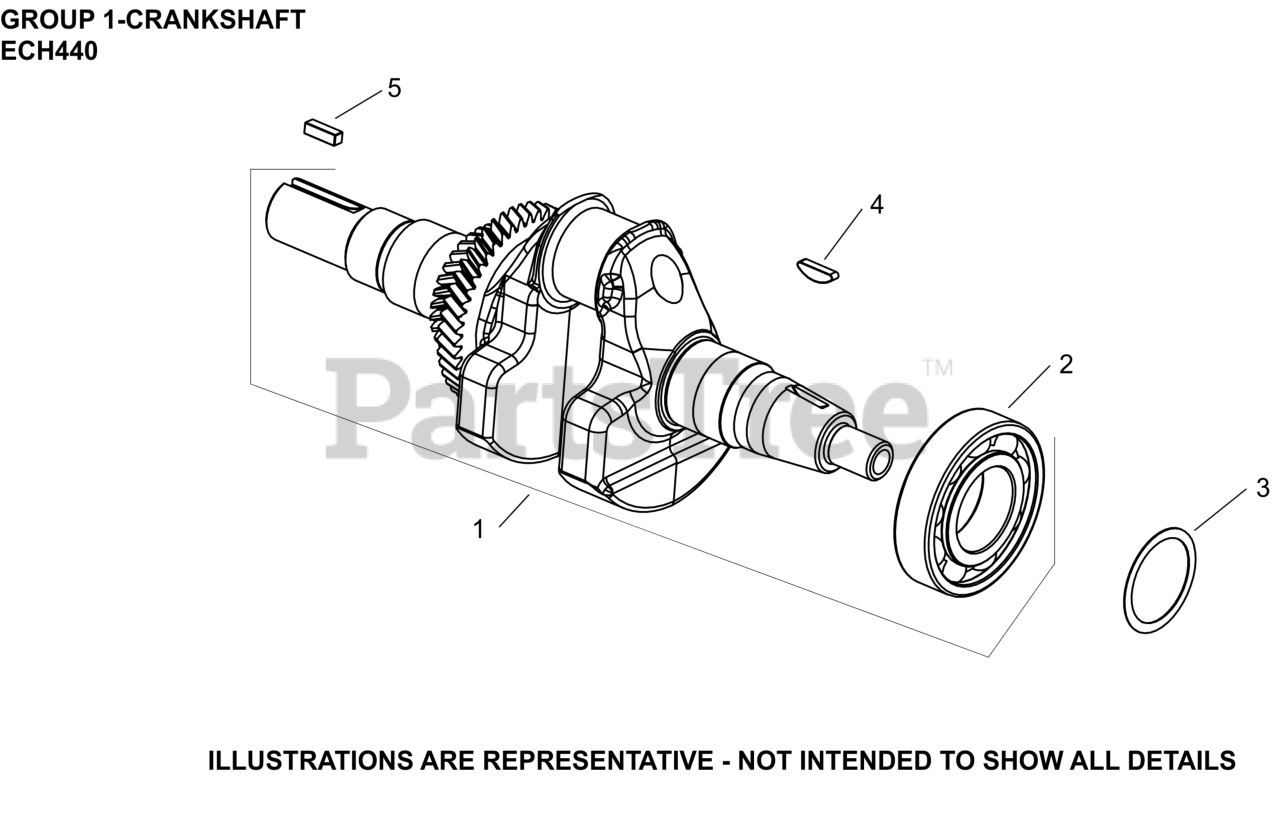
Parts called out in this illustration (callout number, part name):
1	CRANKSHAFT ASSEMBLY
2	BEARING, CRANKSHAFT-(1703034S)
3	KIT, SHIM
4	KEY, FLYWHEEL
